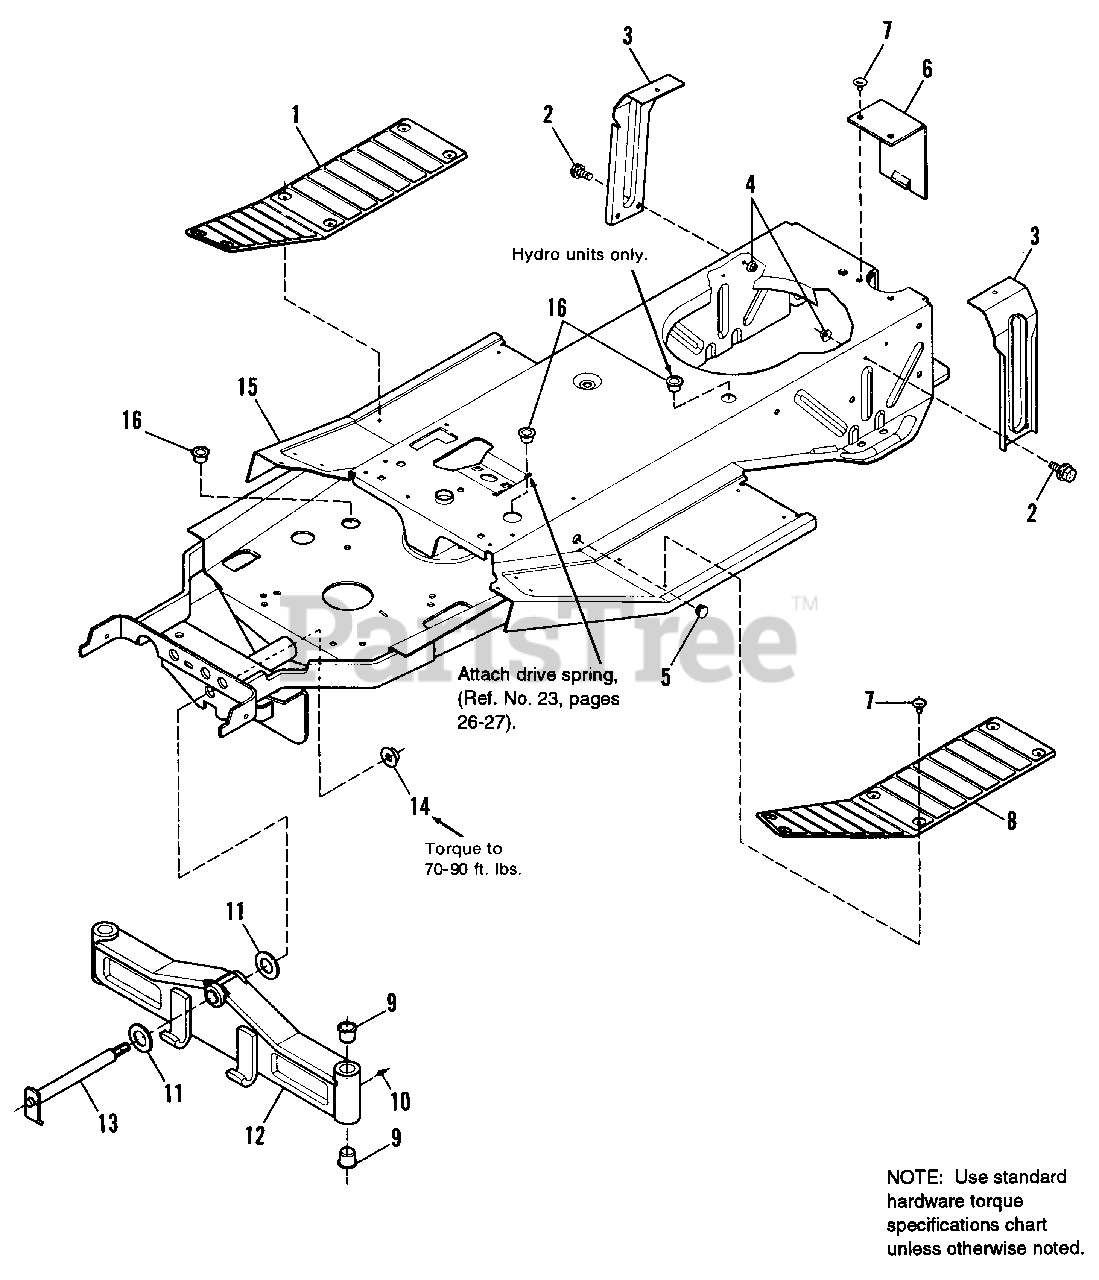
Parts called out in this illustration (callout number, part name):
1	PAD, Footrest, R.H.
2	CAPSCREW, Hex, Flange, Whizlock, 3/8-16 x 1
3	SUPPORT, Seat
4	NUT, Hex, Esna Lock, 3/8-16
6	COVER, Rear (Gear Only)
7	FASTENER, Panel (Qty. 12 on Hydro)
8	PAD, Footrest, L.H.
10	GREASE, Fitting
11	WASHER, Special
12	AXLE ASSY., Front
13	AXLE PIVOT ASSY.
14	NUT, Hex, Full, Lock, 3/4-16
15	FRAME ASSY.
16	BUSHING, Snap
